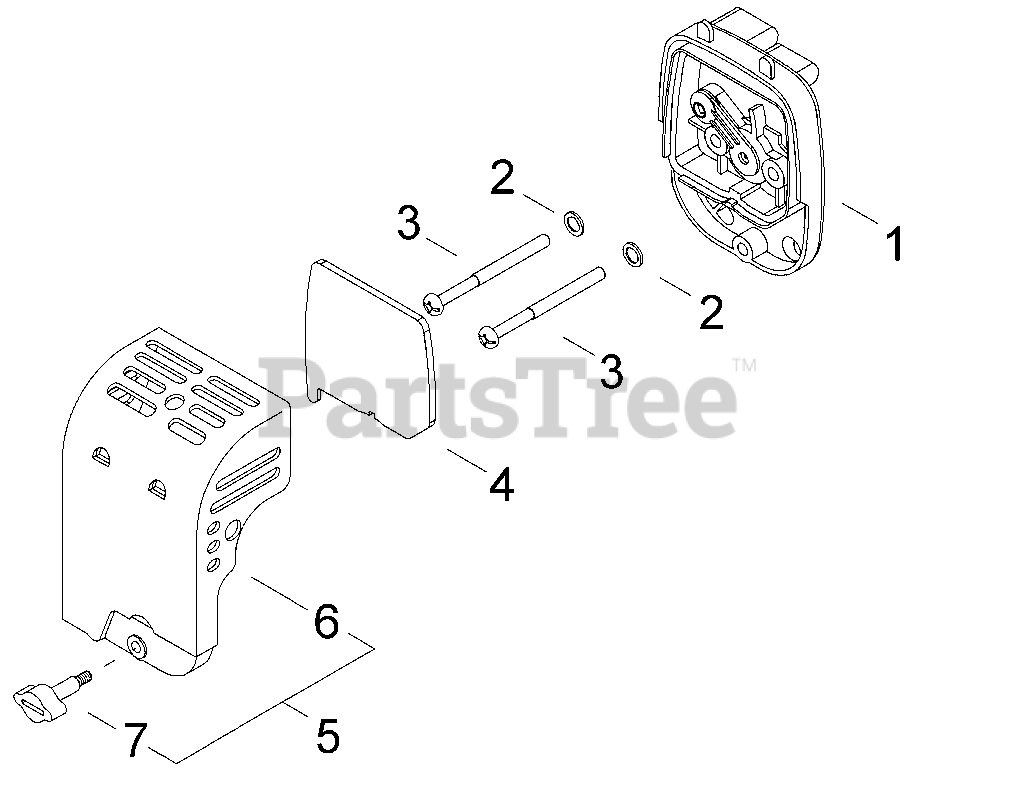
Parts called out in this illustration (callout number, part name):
1	CASE, AIR FILTER
2	WASHER - 5
3	SCREW - 5X60
4	FILTER, AIR
5	AIR FILTER COVER ASSY
6	COVER, AIR FILTER
7	THUMBSCREW
